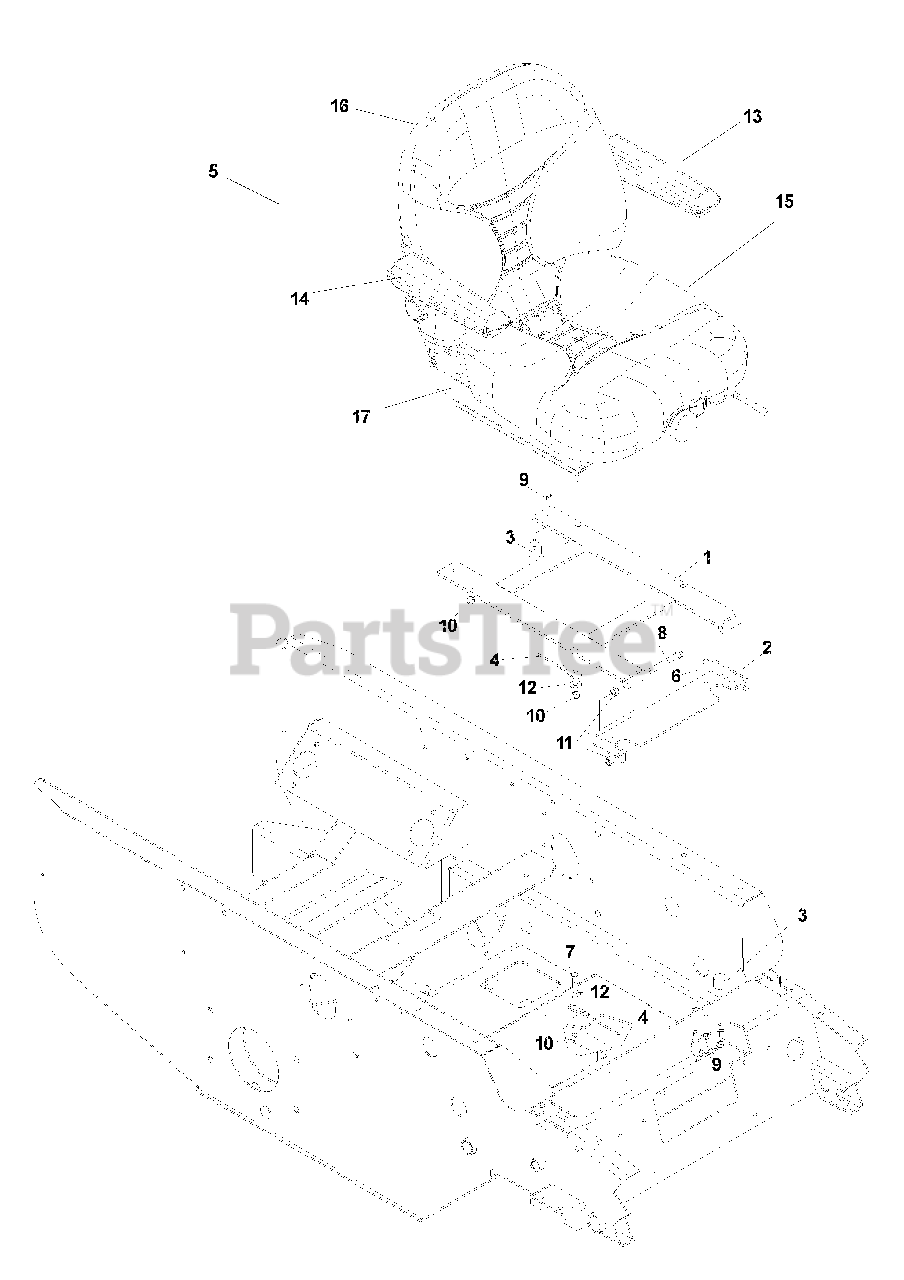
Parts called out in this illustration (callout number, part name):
1	Seat mount
2	Bracket w/decal, seat
3	Stud plate mount
4	Seat lanyard
5	Seat suspension
6	Bolt, 1/4-20 x 3/4
7	Bolt, 5/16-18 x 1
8	Bolt, 3/8-16 x 3
9	Nut, 1/4-20, nyloc
10	Nut, 5/16-18, nyloc
11	Nut, 3/8-16, centerlock
12	Washer, 5/16
13	Armrest kit, left
14	Armrest kit, right
15	Seat cushion kit
16	Back cushion kit
17	Slide kit, seat adjustment
